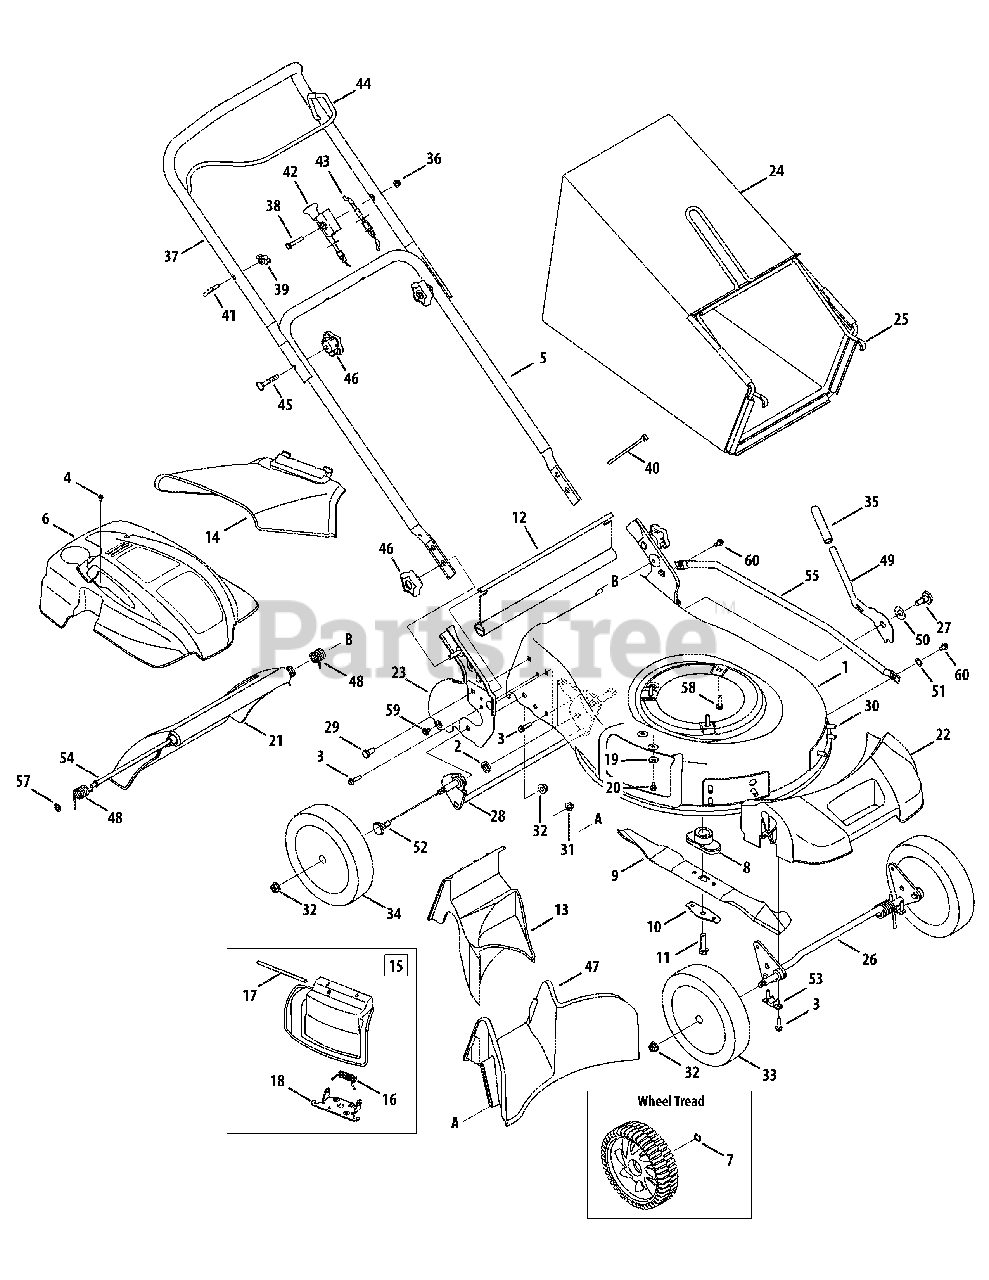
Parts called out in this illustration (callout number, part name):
2	Spacer, .515 x 1.00 x .310 Lg.
3	Screw, 1/4-15 x 1.000
4	Screw, Machine, M4-.7 x 10.00
6	Engine Shroud
7	Washer, Wave .510 x .750 x .017
8	Blade Adapter
9	Mulching Blade
10	Blade Bell Support
11	Screw, 3/8-24 x 1.50
12	Trailing Shield
13	Rear Mulch Plug
14	Side Discharge Chute
15	Mulch Plug
16	Torsion Spring
17	Hinge Pin
18	Chute Deflector Adapter
19	Belleville Washer
21	Rear Door
22	Front Cover
24	Grass Bag
27	Screw, Shoulder .50 x .66
29	HHCS, 5/16-18 x .625
30	Screw, 5/16-14 x .750
31	Nut, Flange Lock, 5/16-18
32	Nut, Flange Lock, 3/8-16
33	Front Wheel
34	Rear Wheel
35	Foam Grip
36	Nut, Flange Lock, 1/4-20
40	Cable Tie
41	Rope Guide
42	Choke Cable
43	Control Cable
45	Bolt Carriage, 5/16-18 x 2.0
46	Star knob
47	Rear Baffle
48	Door Torsion Spring - RH
48	Door Torsion Spring - LH
49	Spring Lever
50	Washer, Bell .510 x 1.14 x .040
51	Washer, Wave .390 x .825 x .016
52	Screw, Shoulder .500 Dia x .434
53	Bushing, Lock .505 Dia x .62
54	Rear Door Pivot Rod
56	Screw, 1/4-20 x .50
57	Nut, Spd.
58	Screw, TT, 3/8-16 x 1.00
59	Screw, #10-16 x .375
